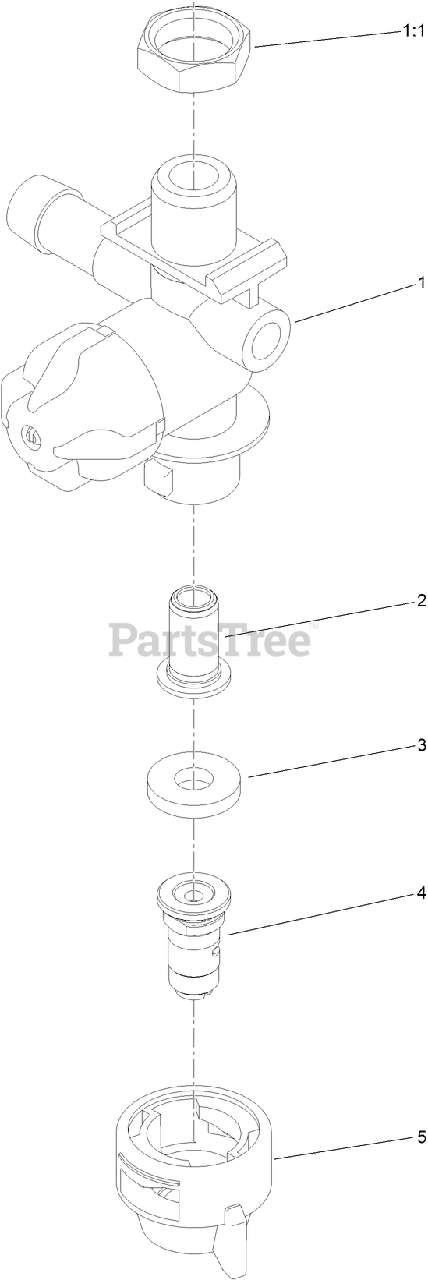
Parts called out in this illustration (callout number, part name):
1	RH NOZZLE BODY ASM
1:1	NUT-NYLON
2	STRAINER-TIP
3	GASKET-SEAL
4	NOZZLE-SPRAY, WHITE
5	CAP-NOZZLE
